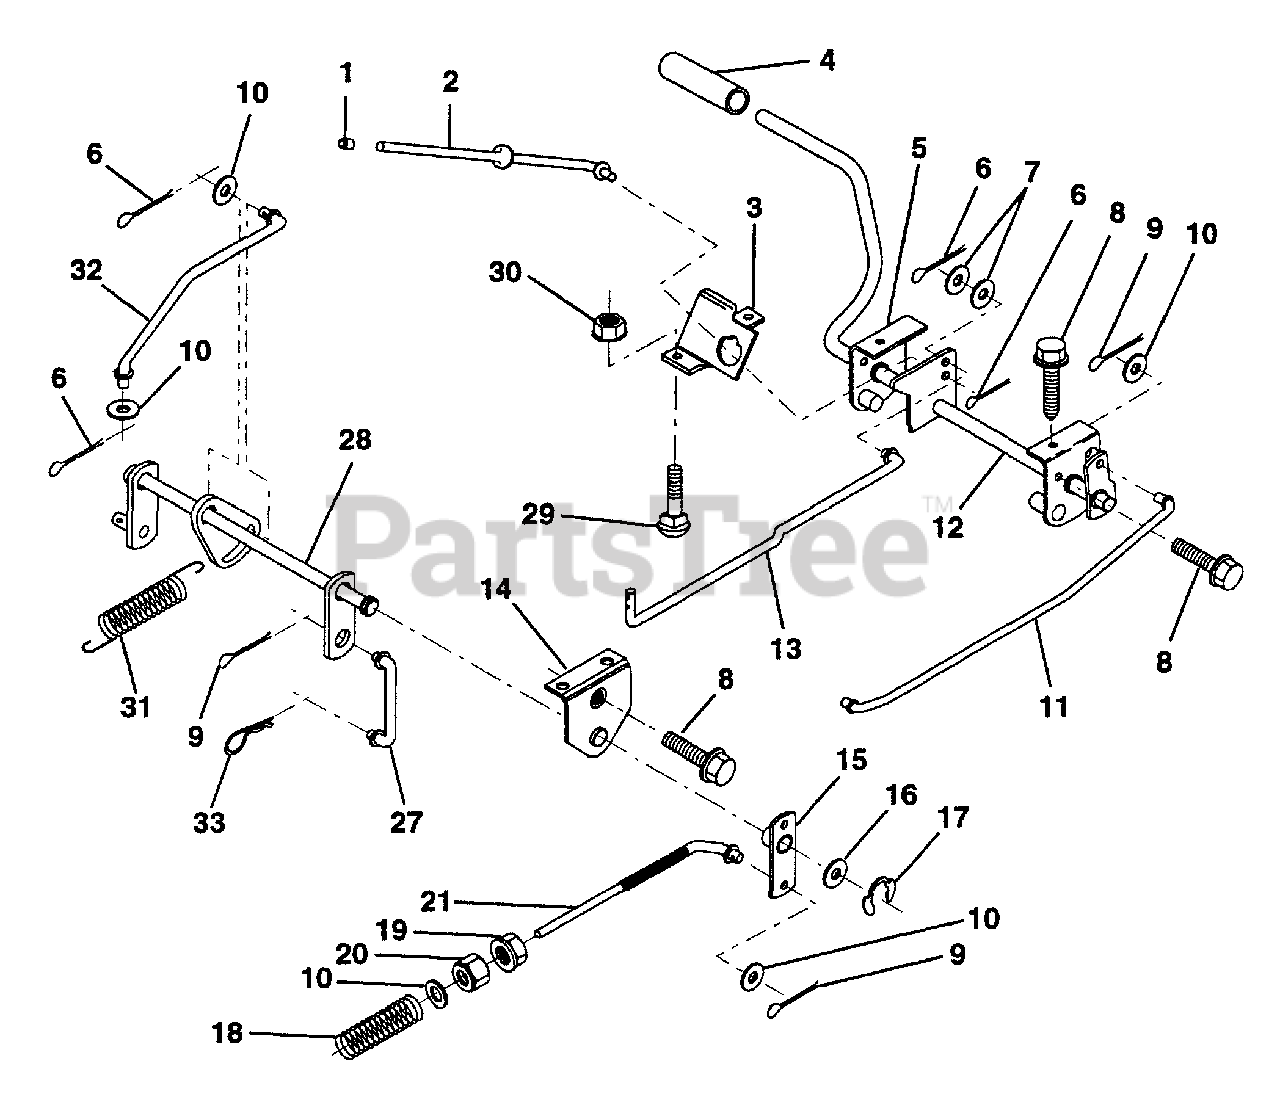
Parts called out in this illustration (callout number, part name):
1	Cap, Plunger
2	Rod, Parking Brake
3	Bracket, Parking Brake
4	Cover, Pedal
5	Bracket, Clutch/Brake Pedal, L.H.
6	Pin, Cotter 3/32 x 3/4
7	Washer 13/32 x 5/8 x 16 Gauge
8	Screw, Hex Head, Thd., Roll. 5/16-18 x 1/2
9	Pin, Cotter 1/8 x 3/4
10	Washer 13/32 x 13/16 x 16 Gauge
11	Rod, Brake, Front
12	Assembly, Clutch/Brake Pedal
13	Rod, Clutch
14	Bracket, Lift Shaft
15	Assembly, Brake, Pivot, Arm
16	Washer 25/32 x 1-1/8 x 16 Gauge
17	Ring, Klip
18	Spring, Brake Rod
19	Nut, Hex, Jam 3/8-16 UNC
20	Nut, Lock Hex w/Ins 3/8-16 Unc
21	Rod, Brake, Rear
27	Link, Lift, Rear
28	Assembly, Rear Mower Lift
29	Bolt, Rd Hd Sqnk 5/16-18 UNC
30	Nut, Hex, Keps 5/16-16 UNC
31	Spring, Counterbalance
32	Link, Lift Lever
33	Retainer Spring
